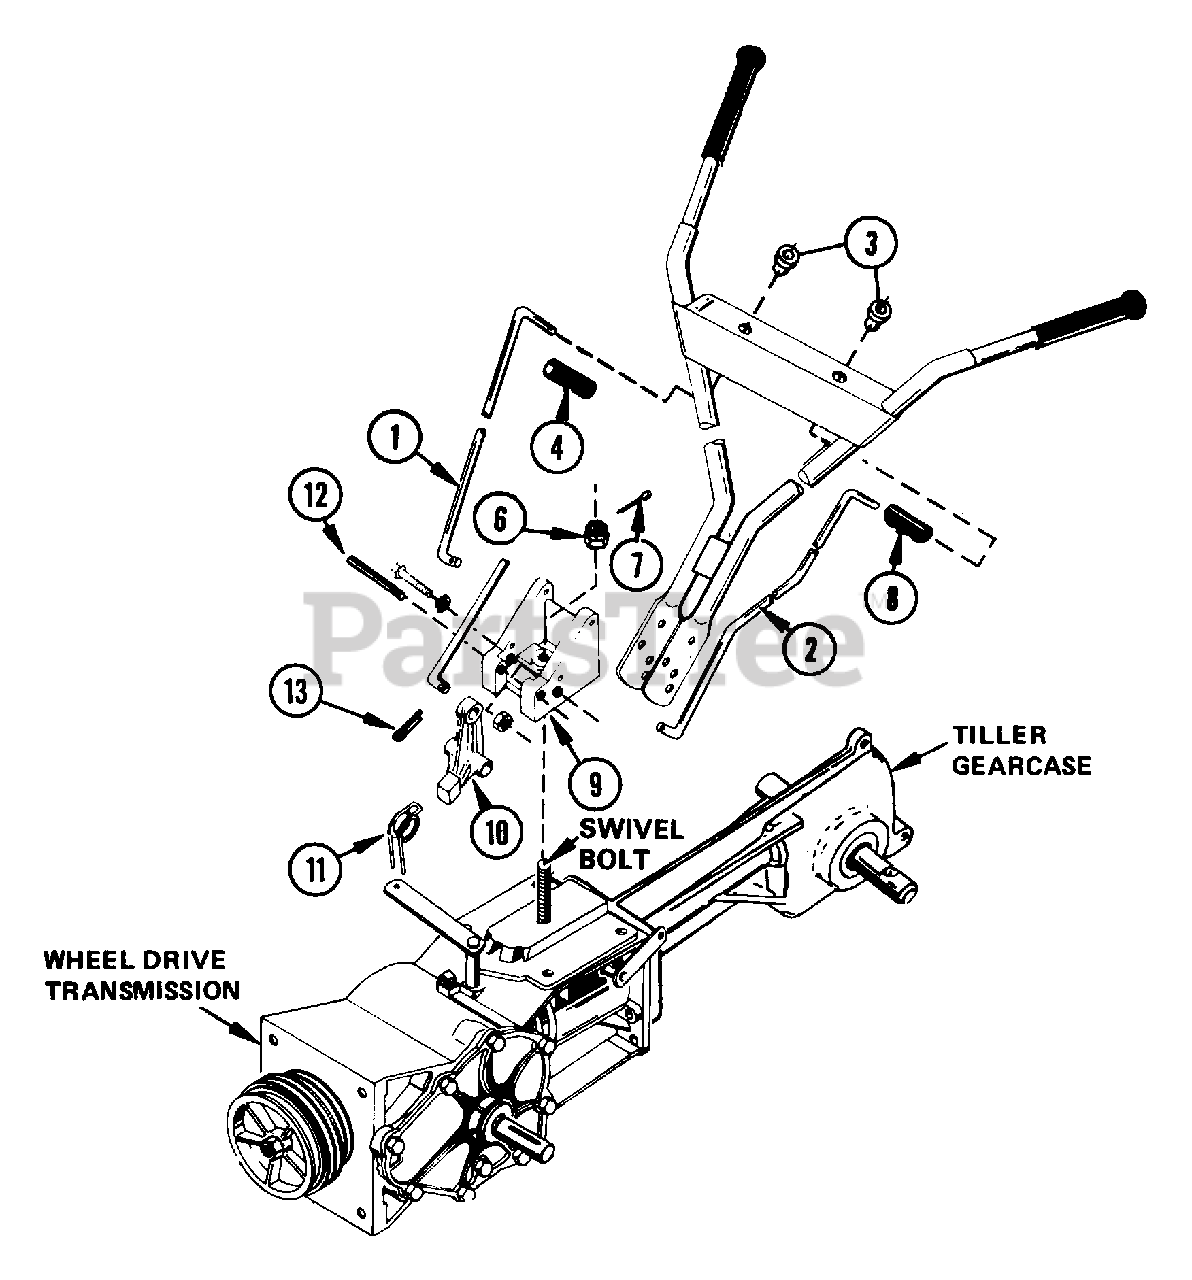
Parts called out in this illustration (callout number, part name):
1	POSITION ROD
2	CLUTCH ROD
3	SNAP BUSHING
4	GRIP
6	NUT-SL .50-13
7	PIN-COTR .12X1.0 PL
8	GRIP
9	HANDLEBAR BRACKET
11	SG-TORS .109X.88X2.25
12	PIN-ROLL .313X2.00
13	PIN-COTR .09X.75 PL
